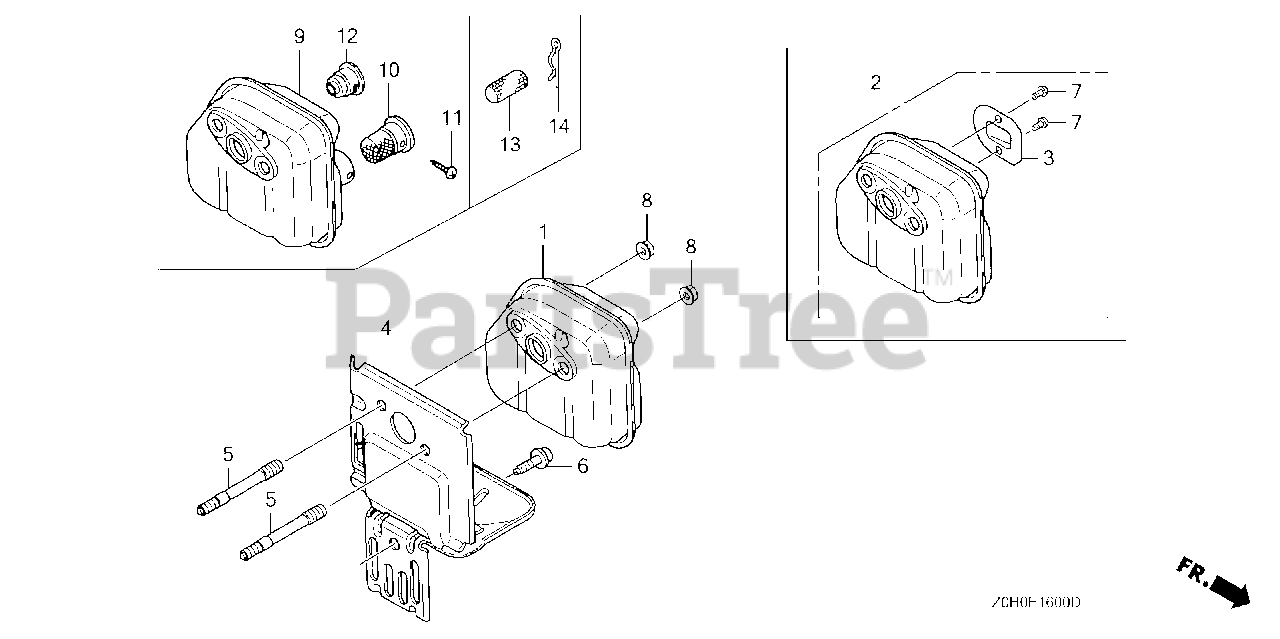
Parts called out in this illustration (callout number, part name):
4	GUIDE, AIR EX.
5	BOLT, STUD (5X52)
6	BOLT, SOCKET (5X10) (CT)
8	NUT, SELF-LOCK (5MM)
9	MUFFLER
9	MUFFLER (ARRESTER)
10	ARRESTER, SPARK
11	SCREW, TAPPING (3X6)
12	FLANGE, BAFFLE
